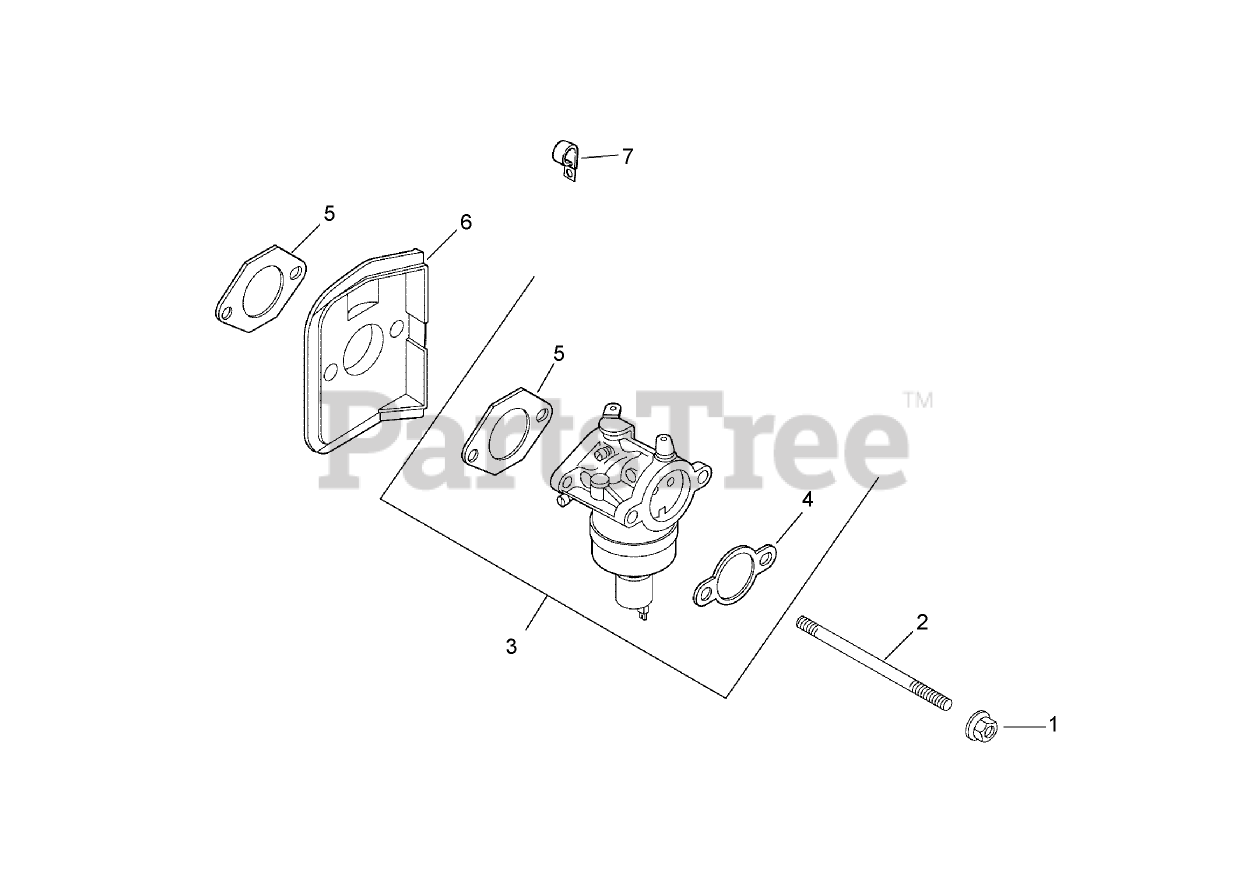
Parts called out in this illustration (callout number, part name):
1	NUT-FLANGE (M6X1.0)
2	Stud (M6x1.0x116)
3	Carburetor Kit (Incl. Ref. #4, 5 qty 1])
4	Gasket-Base, Air Cleaner
5	Gasket-Carburetor
6	Deflector-Heat
7	CLIP-CABLE
